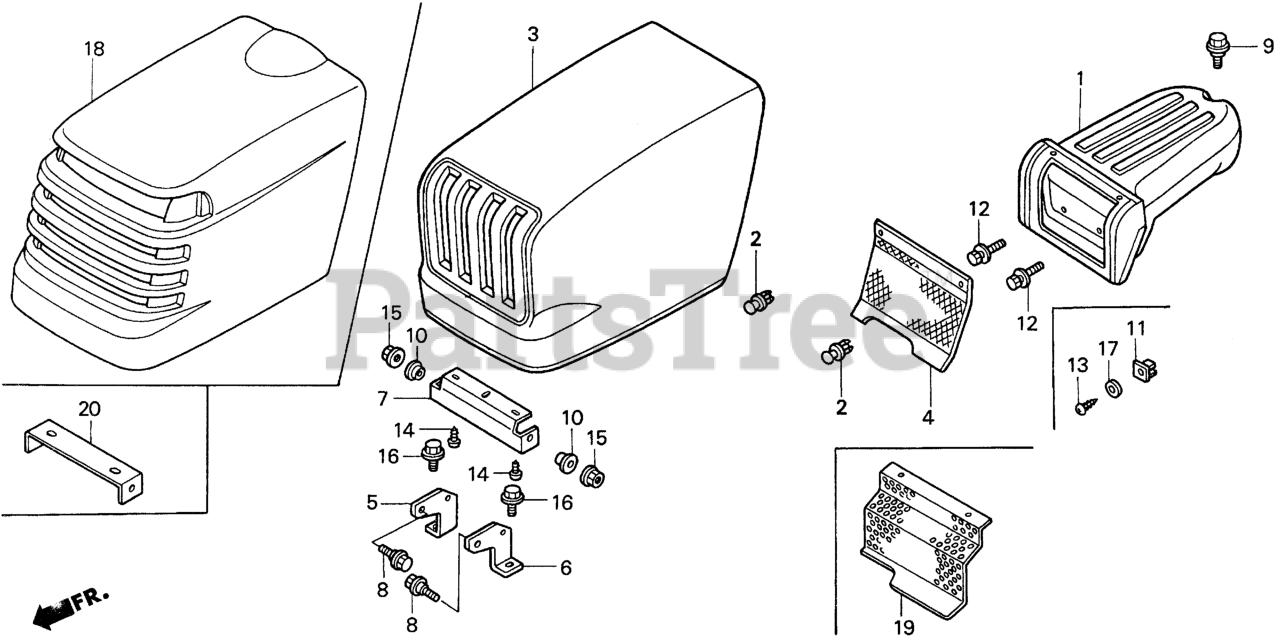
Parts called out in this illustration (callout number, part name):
1	GUIDE, AIR
2	RIVET, SNAP
3	HOOD *R165* (JOLLY RED)
4	SCREEN, DUST
5	HINGE, R. HOOD
6	HINGE, L. HOOD
7	HINGE, HOOD (UPPER)
8	BOLT, FR. FENDER FIXING
9	BOLT, SPECIAL (6MM)
10	COLLAR (6X4)
12	BOLT-WASHER (6X12)
14	SCREW, TAPPING (5X16)
15	NUT, FLANGE (6MM)
16	BOLT, FLANGE (8X16)
